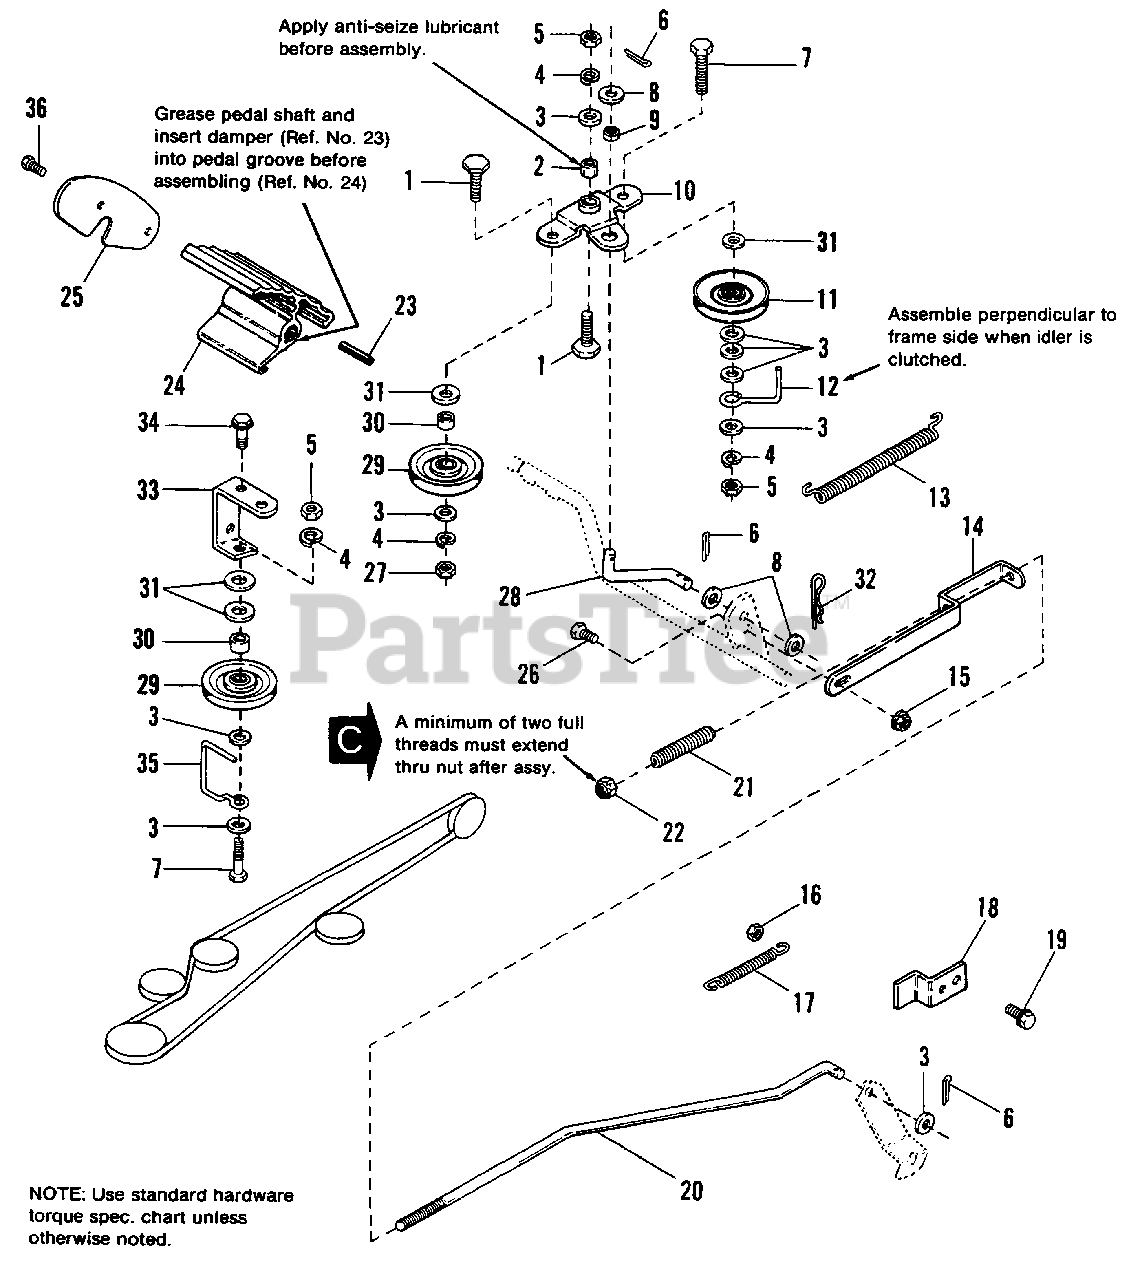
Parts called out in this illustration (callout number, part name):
1	SCREW, Hex, 3/8-16 x 1-1/4, Thin Hd.
3	WASHER, Plain, 5/16
4	LOCKWASHER, 3/8
5	NUT, Hex, 3/8-16
6	PIN, Cotter, 3/4
7	CAPSCREW, Hex Hd., 3/8-16 x 1-3/4
8	WASHER, Plain, 13/32 x 7/8, 14 Ga.
9	BUSHING, Ball
10	ARM ASSY., Clutch
11	PULLEY, Idler
13	SPRING, Tension, Clutch
15	NUT, Hex, Flange Lock, 3/8-16
16	NUT, Jam Lock, 3/8-16
17	SPRING, Brake Return
18	STOP, Brake Lever
19	SCREW, Taptite, 1/4-20 x 1/2
20	ROD, Brake
22	NUT, Hex Lock, 5/16-18
23	DAMPER, Rubber
24	PEDAL, Foot
25	PLATE, End
26	CAPSCREW, Hex, 3/8-16 x 3/4
27	NUT, Hex, Jam, 3/8-16
28	LINK, Clutch Arm
29	PULLEY ASSY.
31	WASHER, 13/32 x 1.10 Ga. Plain
32	CLIP, Spring
33	BRACKET, Idler
34	SCREW, Taptite, 5/16-18 x 5/8
36	SCREW, Taptite, 1/4-20 x 5/8
